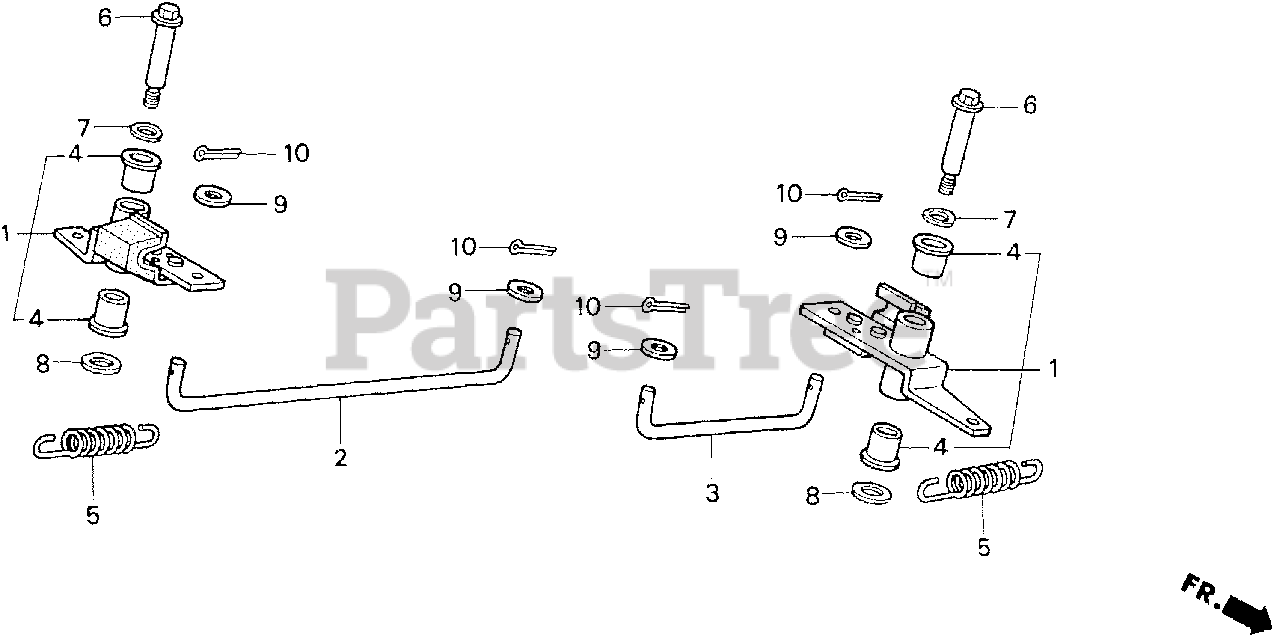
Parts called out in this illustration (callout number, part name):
1	ARM, BLADE BRAKE
2	ROD, BLADE BRAKE (A)
3	ROD, BLADE BRAKE (B)
4	BUSH, BLADE BRAKE
5	SPRING, CHUTE
6	BOLT, BLADE BRAKE
7	WASHER, BLADE BRAKE (12MM)
8	WASHER (8MM)
9	WASHER, PLAIN (6MM)
10	PIN, COTTER (2.5MM) (SOURCE: VINTAGE PARTS INC.)
